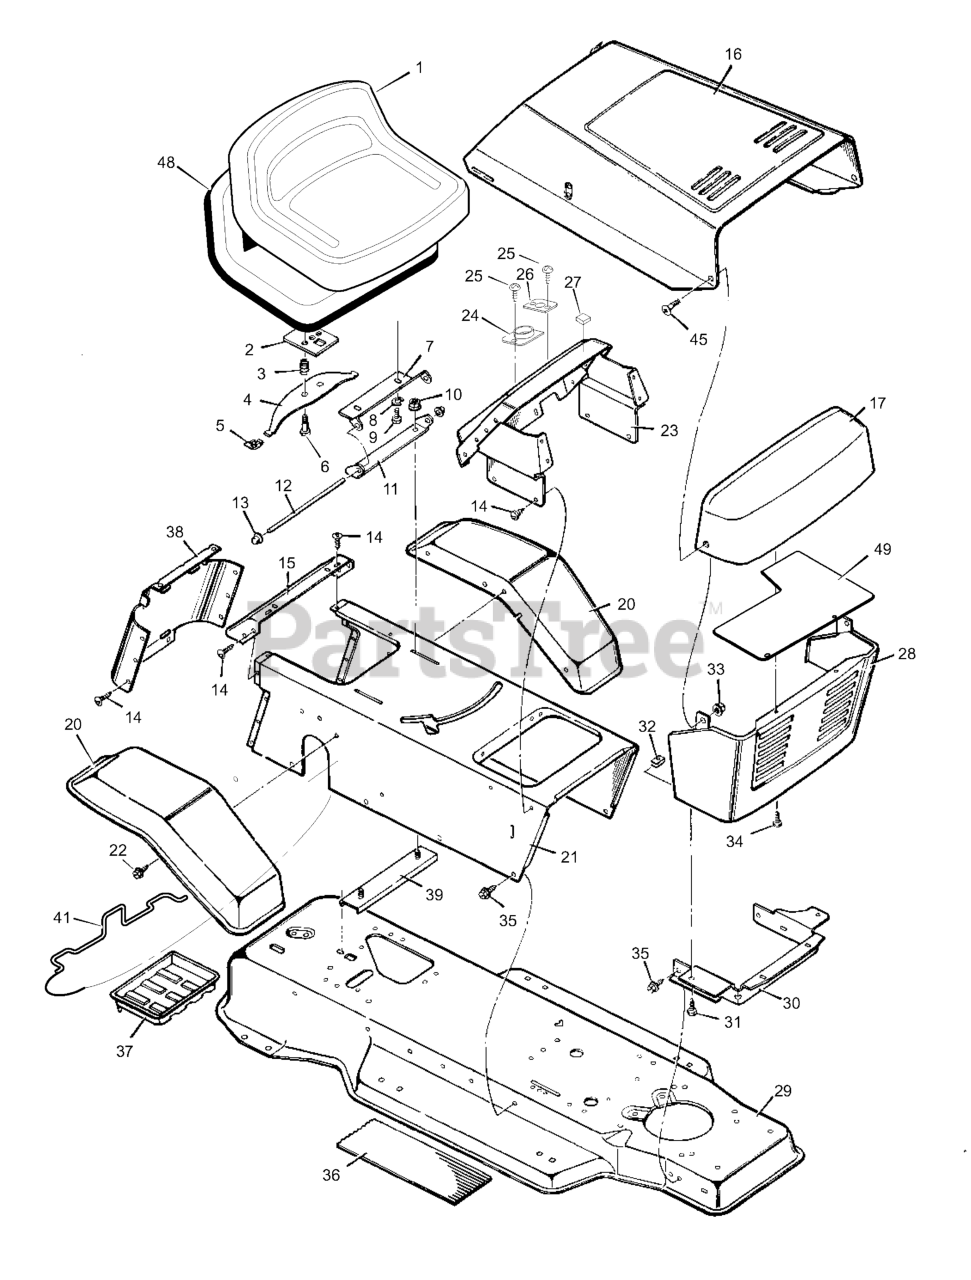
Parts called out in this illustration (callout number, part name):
2	Plate Assembly, Switch
3	Spring, Compression
4	Spring, Seat
5	Glide, Spring
6	Bolt, Shoulder
7	Support, Seat
8	Lockwasher
9	Bolt, Hex
10	Locknut, Flange
11	Bracket, Pivot
12	Rod, Pivot
13	Cap, Push On
14	Screw, Tap
15	Fender, Apron
17	Grille, Upper
21	Console Assembly
23	Dash Panel
24	Bearing, Steering
26	Bearing
27	Bumper
28	Grill, Lower
29	Frame Assembly
30	Support, Grill
33	Locknut, Flange
34	Fastener, Plastic
37	Tray, Battery
38	Cap, Console
39	Channel Assembly
41	Clamp, Battery
45	Bolt, Shoulder
48	Pan, Seat (with foam)
49	Shield, Heat
